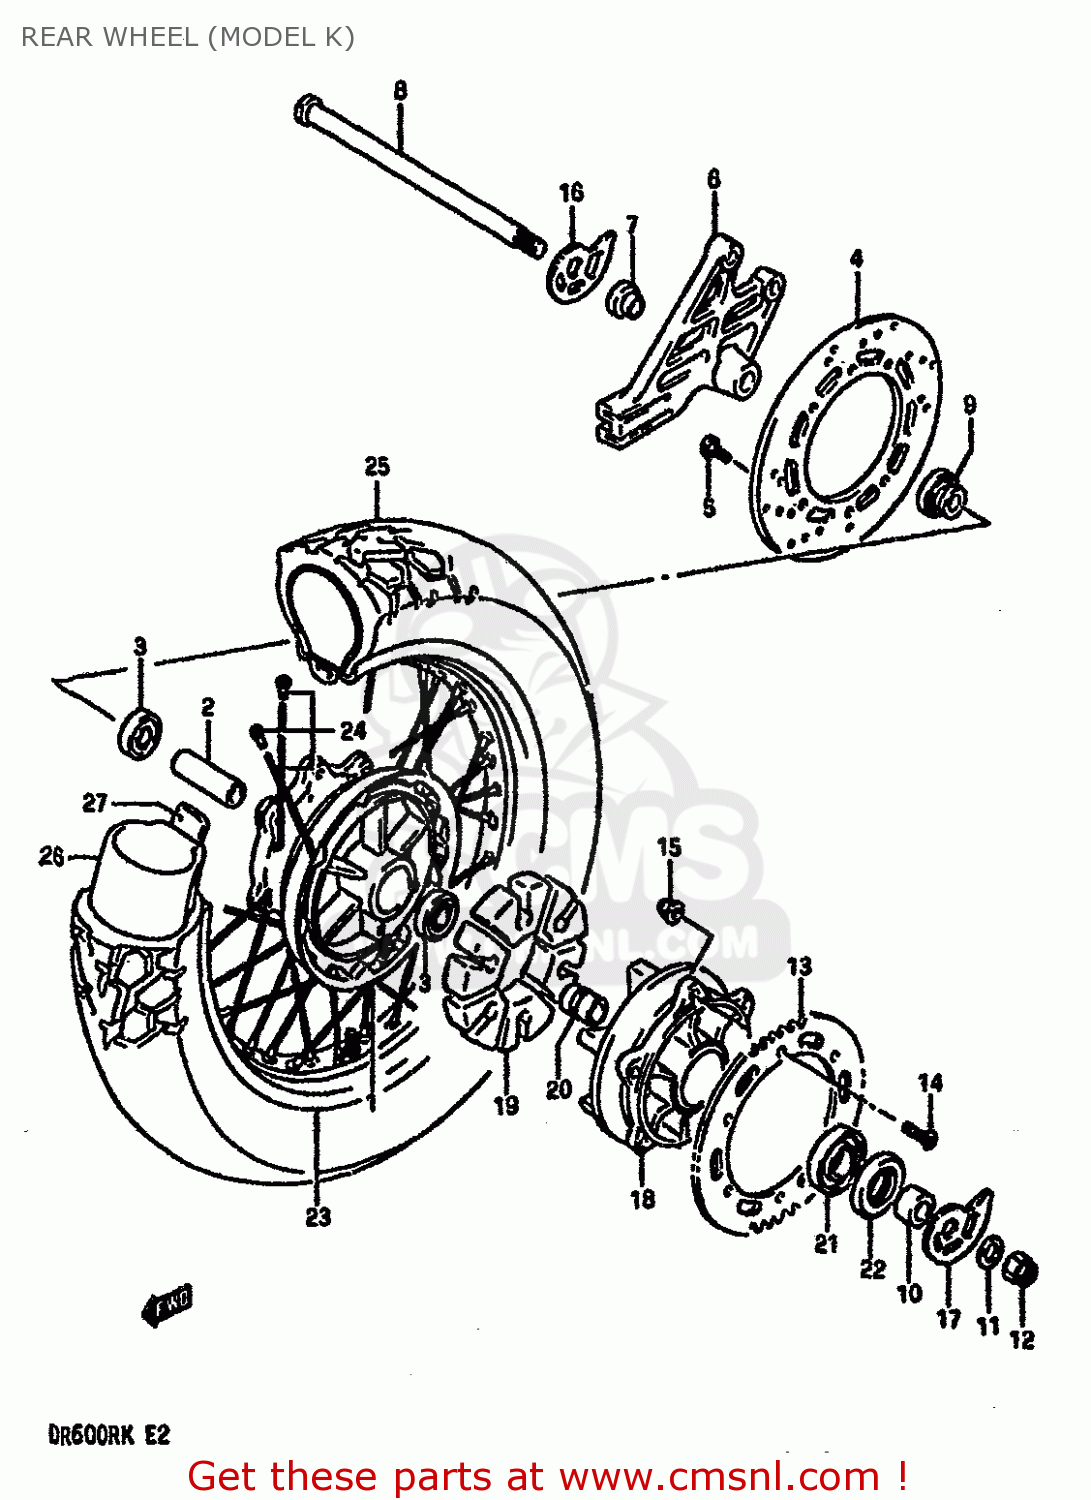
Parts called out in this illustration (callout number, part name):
1	HUB COMP,REAR WHEEL
2	SPACER(17.5X25X78)
3	BEARING
4	DISC,RR BRAKE
5	BOLT,BRAKE DISC
6	BRACKET,RR CALIPER
7	SPACER (17X21X10)
8	AXLE,RR
9	SPACER,RR AXLE,L
10	SPACER(17X33X22.4)
11	WASHER (17X30X3.2)
12	NUT
13	SPROCKET,REAR
14	BOLT(8X30.5)
15	NUT
16	ADJUSTER,CHAIN,RH
17	ADJUSTER,CHAIN,LH
18	DRUM,REAR SPROCKET
19	ABSORBER,RR HUB SHOCK
20	RETAINER,RR SPROCKET DRUM
21	BEARING(25X62X17)
22	SEAL,OIL(33X62X7)
23	RIM,REAR WHEEL (MT2.50X17) (GOLD)
24	SPOKE SET,RR
25	TIRE
26	TUBE ASSEMBLY,WHEEL,INNER
27	NUT
28	ADJUSTER,CHAIN RH
29	ADJUSTER,CHAIN LH
30	DRUM,RR SPROCKET MOUNTING
31	CUSHION,REAR DRUM
32	RETAINER,RR SPROCKET DRUM
33	BEARING(25X52X15)
34	RIM,REAR WHEEL
35	SPOKE SET,REAR WHEEL
36	TIRE
37	TUBE ASSEMBLY,WHEEL,INNER
38	PROTECTOR,INNER TUBE
